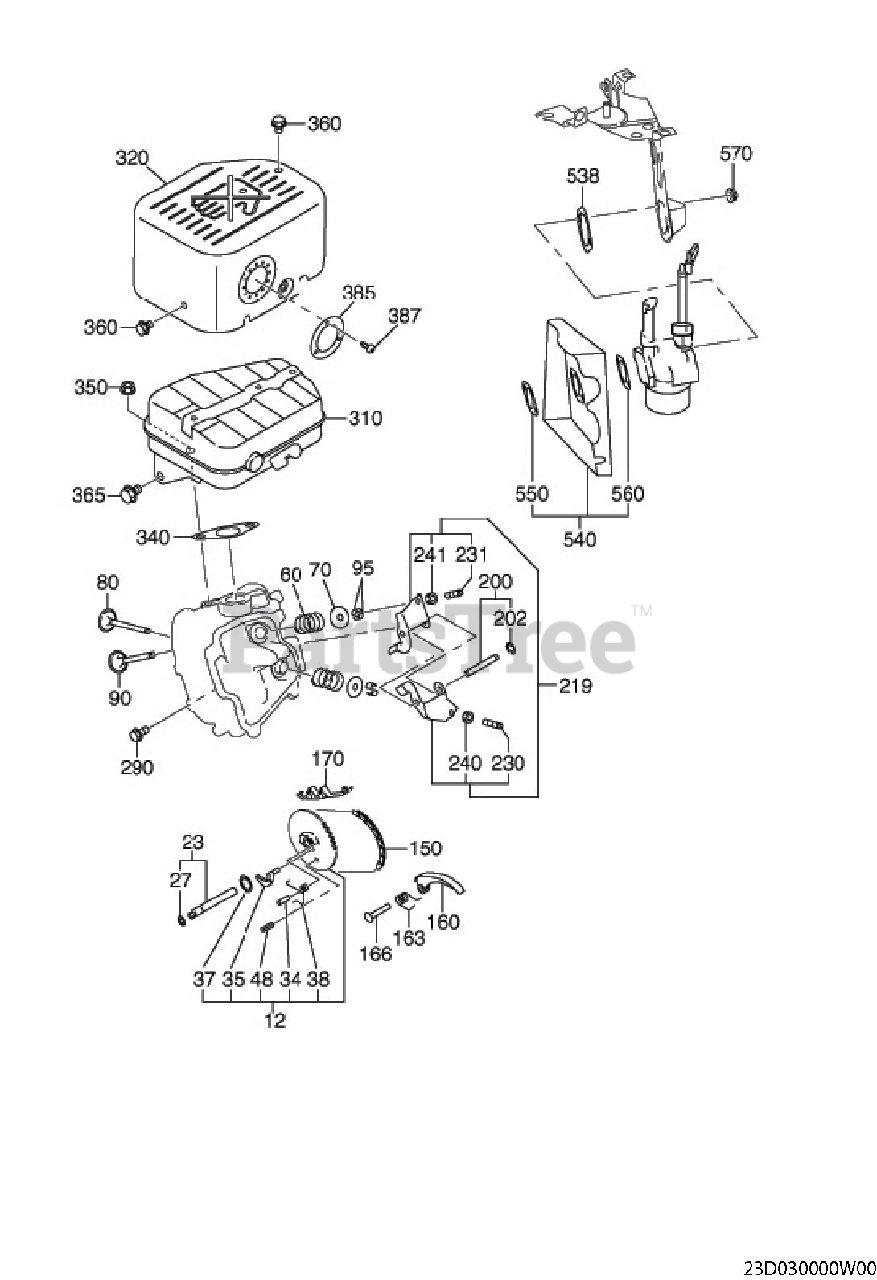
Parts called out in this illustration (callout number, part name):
23	PIN(CAM SHAFT)CP
34	SPRING PIN
38	RETURN SPRING
60	VALVE SPRING
70	SPRING RETAINER
150	TIMING CHAIN CP
163	SPRING(TENTIONER)
166	PIN(TENTIONER)
202	CLIP
219	ROCKER ARM AY SET
230	ADJUST SCREW
231	ADJUST SCREW
240	NUT
241	NUT
290	FLANGE BOLT
320	Muffler Cover CP
340	GASKET(MUFFLER)
350	FLANGE NUT
360	FLANGE BOLT
365	FLANGE BOLT
385	TAIL SCREEN UN
387	TAPPING SCREW
538	GASKT 3
550	GASKET 2
560	GASKET 1
570	FLANGE NUT
